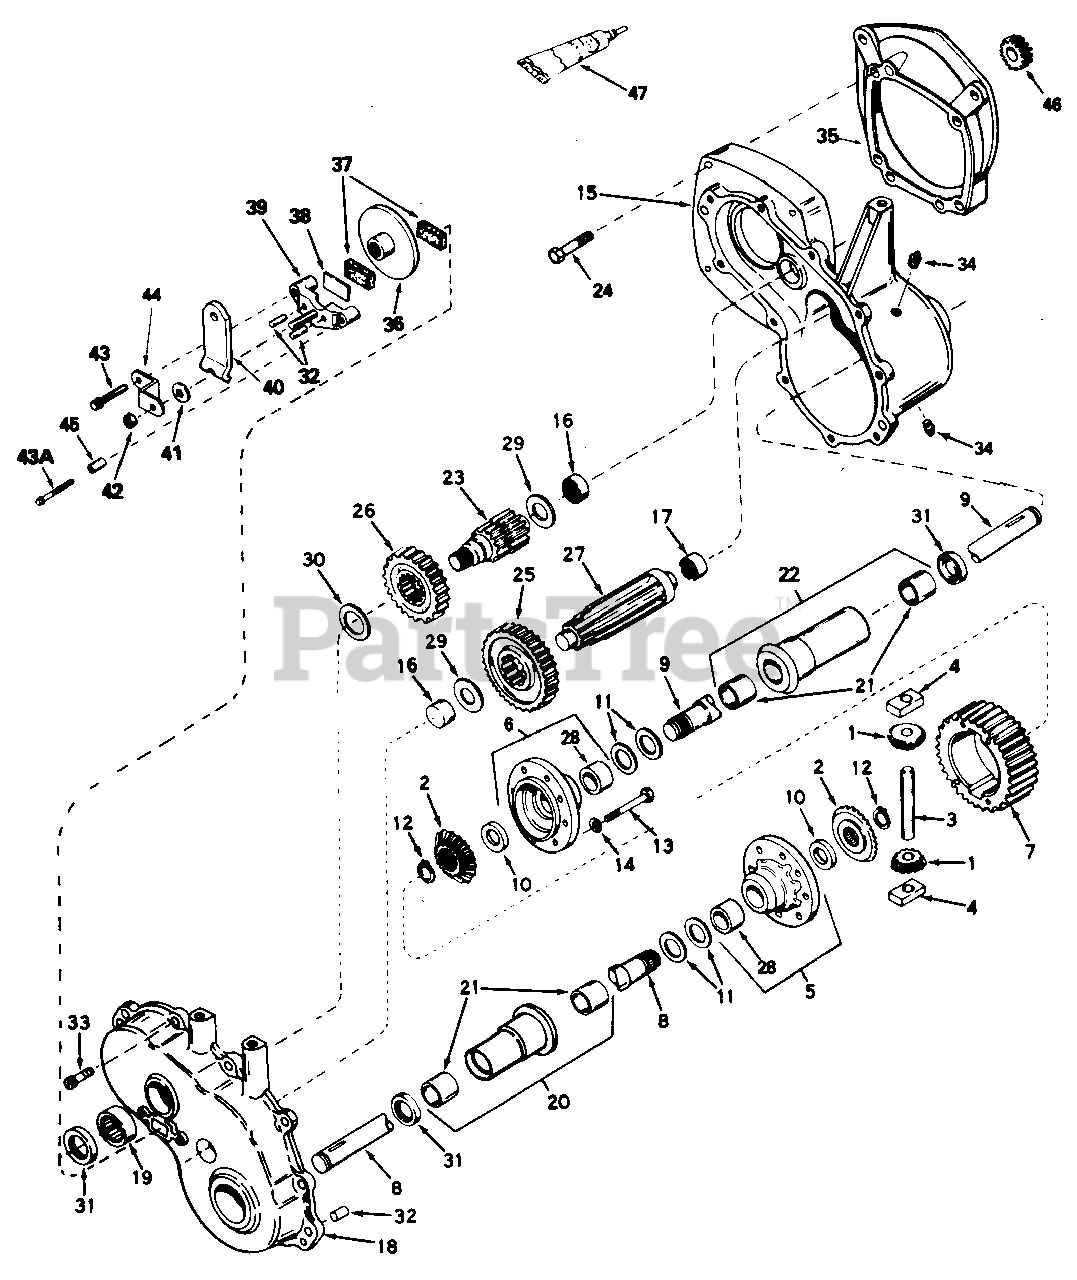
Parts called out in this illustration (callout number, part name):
1	Pinion, Bevel
2	Gear, Bevel
3	Pin, Drive
4	Block, Drive
5	Carrier Ass'y., Differential
6	Carrier Ass'y., Differential
7	Gear, Ring
8	Axle (13-1/16" Long)
9	Axle (19-1/8" Long)
10	Washer
11	Washer. Thrust
12	Ring. Snap
13	Screw, Hex Hd., 1/4-20 x 2-1/4
14	Lock Washer, 1/4"
15	Case Ass'y
16	Bearing, Needle
17	Bearing, Needle
18	Cover Ass'y
19	Bearing, Needle
20	Housing & Bushing Ass'y (6-5/8" Long)
21	Bushing
22	Housing & Bushing Ass'y (12-45/64" Long)
23	Shaft, Brake
24	Screw, Hex Hd., 3/8-16 x 2
25	Gear, Output
26	Gear, Idler
27	Shaft, Output
28	Bushing
29	Washer
30	Washer
31	Seal, Oil
32	Pin, Dowel
33	Screw, Hex Washer Hd Thread Forming, 1/4-20 x 1
34	Plug, Pipe
35	Plate, Adapter
36	Disc, Brake
37	Pad, Brake
38	Plate, Brake Pad
39	Holder, Brake Pad
40	Lever, Brake
41	Washer, Flat
42	Lock Nut, 5/16-24
43	Screw, Flanged Hex Hd Thread Forming, 1/4-20 x 1-1/4
43A	Screw, Flanged Hex Hd Thread Forming, 1/4-20 x 2-1/4
44	Bracket
45	Spacer
46	Gear, Spur (18 Teeth)
47	Gasket Eliminator
